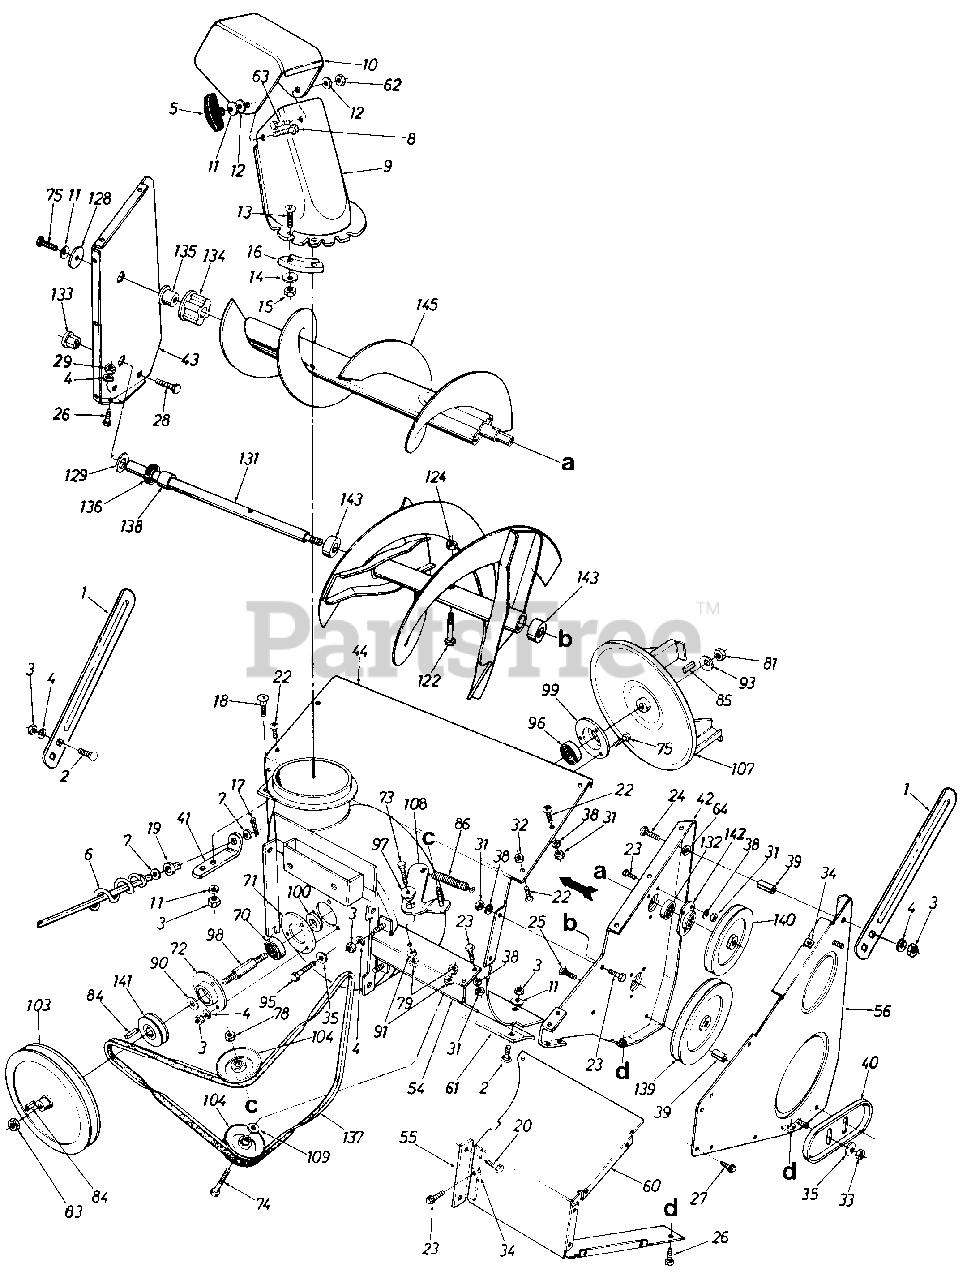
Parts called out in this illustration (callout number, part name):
1	Guide Blade
2	Carriage Bolt 5/16-18 x .62"
3	Hex Nut 5/16-18 Thd.
4	L-Wash. 5/16" I.D.
5	Hand Knob Ass'y.
6	Chute Crank Ass'y.
7	Fl-Wash. .385" I.D. x .62"
8	Carriage Bolt 5/16-18 x 1.0"
9	6" Dia. Lower Chute
10	6.0 Dia. Upper Chute
11	Bell-Wash. .345 I.D. x .88 O.D. x .06
12	Fl-Wash. .344 I.D. x .125 O.D. x .125
13	Truss Mach. Scr. 1/4-20 x .75" Lg.
14	Bell-Wash. 1/4" I.D.
15	Hex Nut 1/4-20 Thd.
16	Chute Flange Keeper
17	Cotter Pin
18	Carriage Bolt 5/16-18 x .75'
19	Bushing
20	Hex Self-Tap Scr. 5/16-24 x .5" Lg.
22	Truss Mach. Scr. 1/4-20 x .5"
23	Hex Bolt 1/4-20 x .5" Lg.
24	Carriage Bolt 5/16-18 x 1.75
25	Carriage Bolt 3/8-16 x 1.75
26	Hex Self-Tap Scr. 5/16-24 x .75" Lg.
27	Hex Self-Tap Scr. 1/4-20 x .38" Lg.
28	Carriage Bolt 3/8-16 x .62"
29	Hex Nut 5/16-24 Thd.
31	Hex Nut 5/16-18 Thd.
32	Hex Ins. L-Nut 1/4-20 Thd.
33	Hex Jam Nut 3/8-16 Thd.
34	Speed Clip
35	Bell-Wash. 3/8" I.D.
38	L-Wash. 1/4" I.D.
39	Spacer .375 I.D. x 1" Lg.
40	Slide Shoe
42	Spiral Housing Plate R.H.
43	Spiral Housing Plate L.H.
44	24" Spiral Hsg. Ass'y.
54	V-Channel
55	Support Bracket
56	Side Cover Ass'y.
60	Belt Cover 6.42"
63	Truss Mach. Scr. 5/16-18 x .75"
64	Push Speed Nut
70	Ball Bearing
71	Spindle Reinforcement Plate
72	Open Brg. Housing
73	Hex Bolt 3/8-24 x .75" Lg.
74	Hex Bolt 3/8-24 x 1.25" Lg.
75	Hex Bolt 5/16-18 x 1" Lg. (Gr. 5)
78	Hex Ins. L-Nut 3/8-24
79	Hex Nut 3/8-24 Thd.
81	Hex Jam Nut 5/8-18 Thd.
83	Hex L-Nut 5/8-18 Thd.
84	Sq. Key 3/16" x .75"
85	Sq. Key 3/16" x 1.5"
86	Ext. Spring 3/4 O.D. x 4" Lg.
90	Fl-Wash. .635 I.D.
91	L-Wash. 3/8" I.D.
93	Bell-Wash. .630
95	Shld. Bolt .50 Dia. x 2.11 Lg.
96	Ball Bearing
97	Shld. Spacer .625 I.D.
98	Fan Spindle
99	Bearing Hsg. Ass'y.
100	Spacer .790 I.D.
103	5/8 V-Pulley 7.5" O.D.
104	V-Idler Pulley 3.5" O.D.
107	11" Dia. Blower Fan Ass'y.
108	Idler Bracket Ass'y.
109	Fl-Wash. .40 I.D.
122	Shear Bolt 5/16-18 x 1.5"
124	Hex Ins. L-Nut 5/16-18 Thd.
128	Flat Washer .32" I.D.
129	Fl-Wash. .76" I.D.
131	Spindle Shaft
132	Ball Brg. .62 I.D.
133	Hex Flange Brg.
134	Tubing Support Brg.
135	Shaft Pin
136	Spacer 1.25 I.D. x 1.5
137	V-Belt
138	Spacer
139	1/2 V-Pulley 9" O.D.
140	1/2 V-Pulley 5.5" O.D.
141	1/2 V-Pulley 2.75"
142	Bearing Housing
143	Sleeve Brg. .75 I.D.
145	24" Auger Ass'y.
